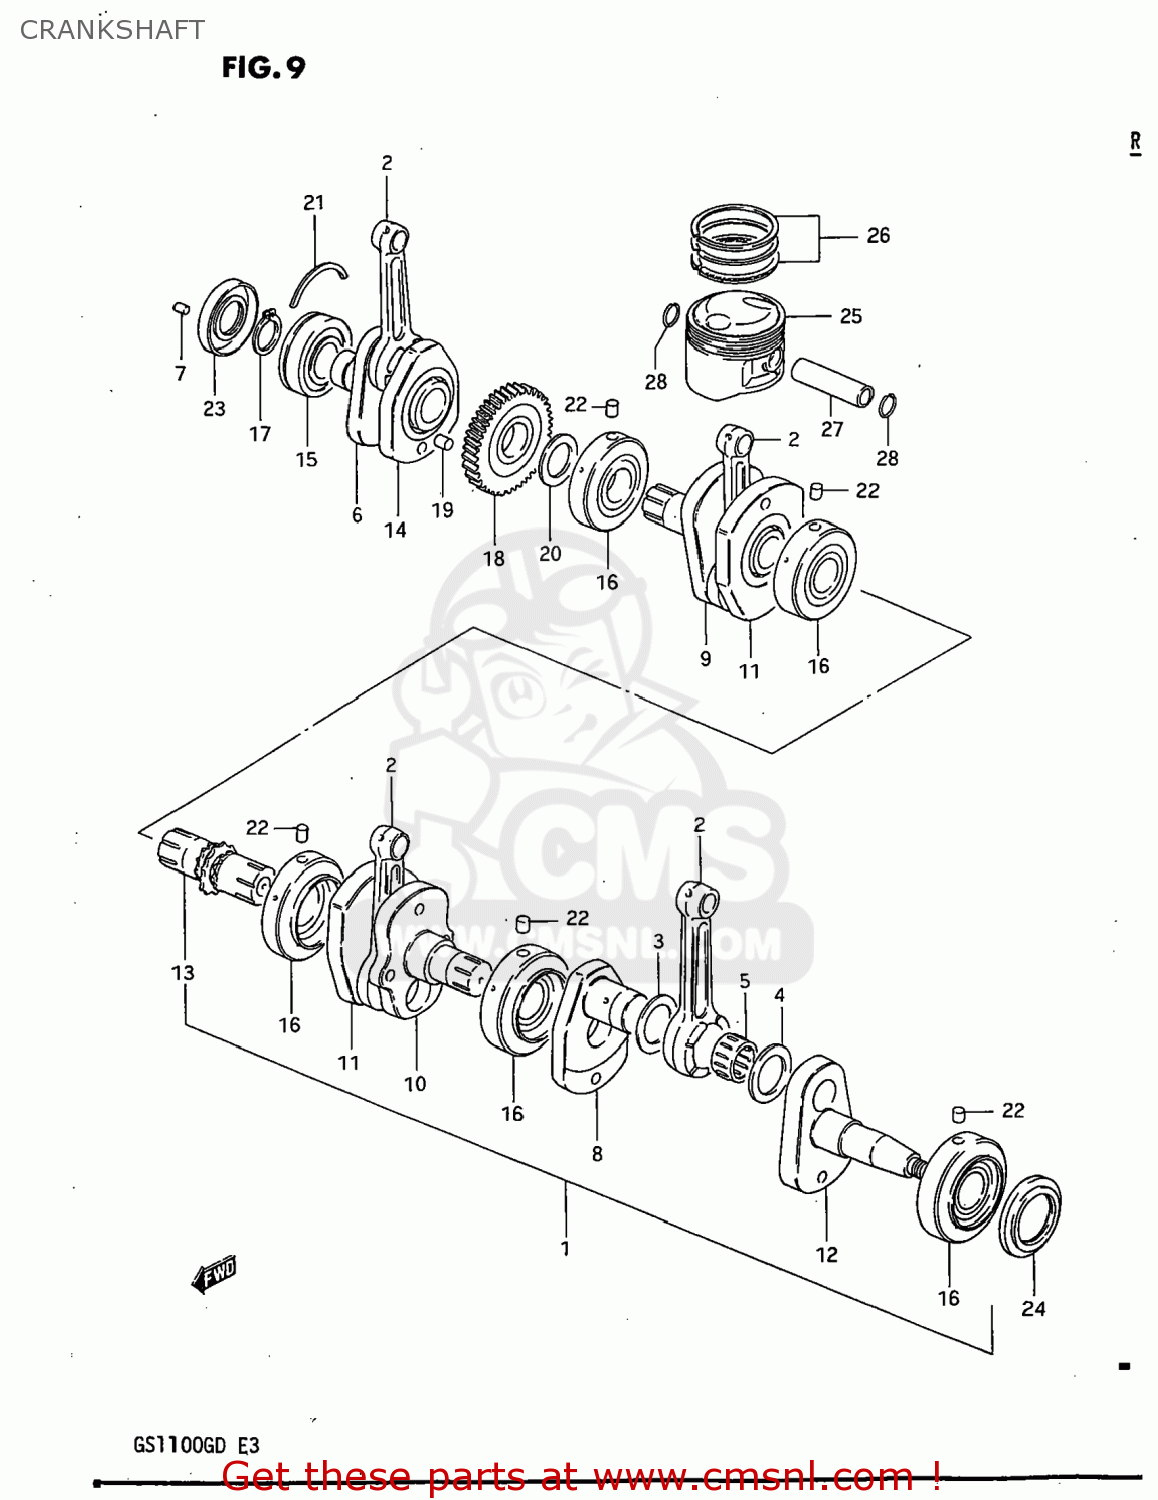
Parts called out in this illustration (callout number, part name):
1	CRANKSHAFT ASSEMBLY
2	ROD,CONNECTING
3	WASHER(31X48.5X1)
4	WASHER(31X48.5X2)
5	BEARING
6	CRANKSHAFT,RIGHT
7	PIN
8	WEB,CRANK
9	CRANKSHAFT,MIDDLE,RIGHT
10	CRANKSHAFT,MIDDLE,RIGHT
11	WEB,CRANK,MIDDLE
12	CRANKSHAFT,LEFT
13	SHAFT,TIMING CHAIN DRIVE
14	WEB,CRANK,RIGHT
15	BEARING(30X72X19)
16	BEARING
17	CIRCLIP,30MM
18	GEAR,PRIMARY DRIVE
19	PIN
20	WASHER
21	C RING
22	PIN
23	SEAL,OIL(30X72X11)
24	SEAL,OIL(47.3X60X6.5)
25	PISTON
26	RING SET,PISTON
27	PIN,PISTON
28	CIRCLIP
